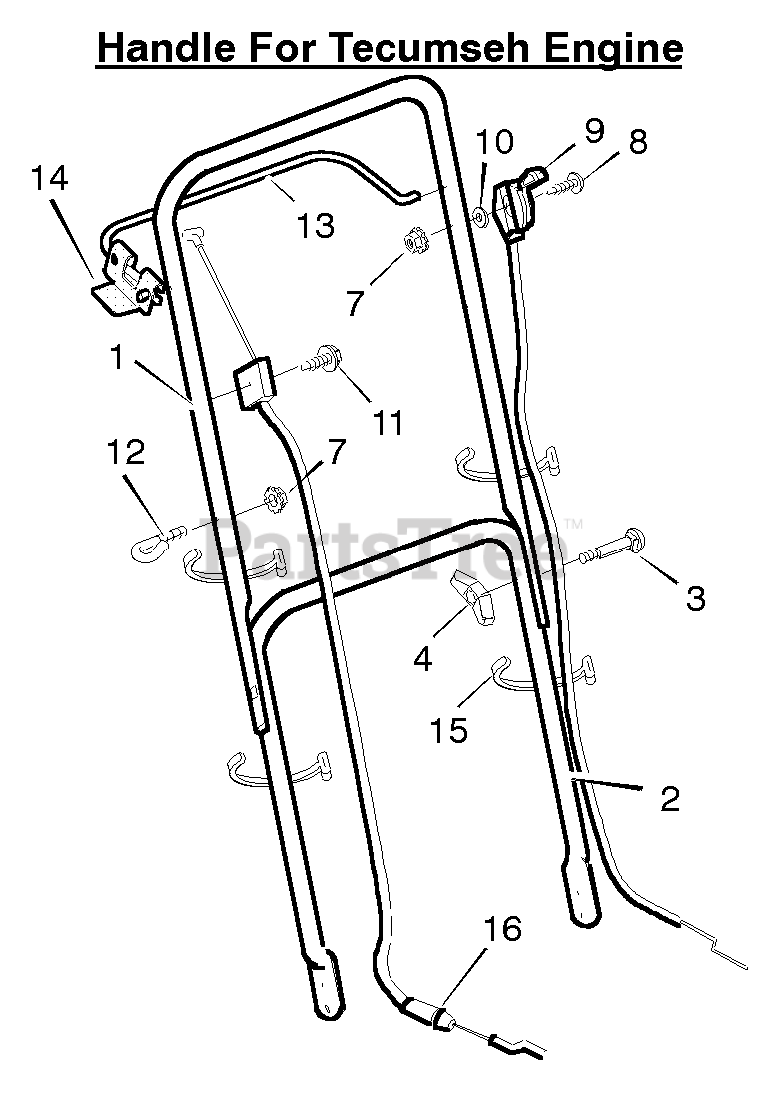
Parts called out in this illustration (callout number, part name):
1	Handle, Upper (Black)
2	Handle, Lower (Black)
7	Locknut
9	Throttle Control
12	GUIDE, ROPE
13	Engine Stop Lever
14	Bracket, Stop Lever
15	Fastener, Cable
16	Engine Stop Cable
